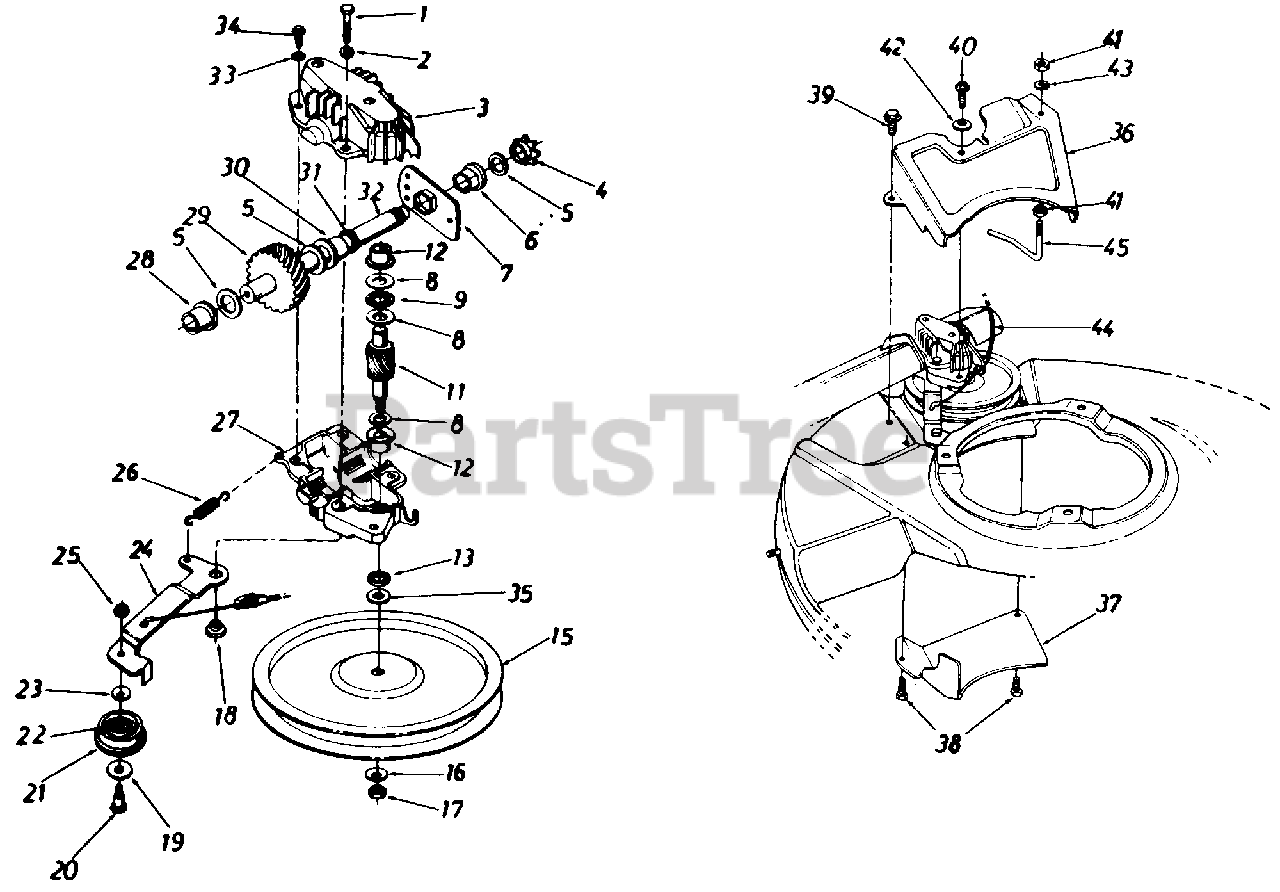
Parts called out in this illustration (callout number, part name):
1	Hex Bolt 1/4-20 x 1.25" Lg. w/Patch
2	L-Wash. 1/41" I.D.
3	Upper Hsg. Half
4	#48 Sprocket 7 Tooth x 1/2 Pitch
5	Fl-Wash. 518" I.D. x .030
6	Hex Flange Brg. .631" I.D.
8	Thrust Wash. .382" I.D. x .70" O.D.
9	Thrust Bearing .375" I.D. x.812" O.D.
11	11 Tooth Helical Gear
12	Flange Bearing
15	Fl-Pulley 5.06" I.D.
16	Bell-Wash. .265" I.D. x 75"
17	Hex Nut 1/4-28 L.H. Thd.
18	Shld. Spacer .375" Dia. x .170
19	Fl-Wash. .390" I.D. x 1.0"
20	Shld. Bolt .375" Dia. x .40"
21	Fl-ldler Plastic 1.50" Dia.
22	Needle Brg. .375" x .31"
23	Bell-Wash. .265" I.D. x .75"
24	Idler Brk't. Ass'y t
25	Hex Patch L-Nut 1/4-28 Thd.
26	Extension Spring 1.12" Lg.
27	Lower Hsg. Half
28	Flange Bearing .56 Dia.
29	33 Tooth Helical Gear
30	Flange Bearing .629 Dia.
31	Oil Seal .625 Dia.
32	Gear Sprocket Shaft
33	L-Wash. #10 I.D.
34	Hex B-Tap Scr. #10 x .62"
35	Hex Washer .26" x .88n
39	Hex AB-Tap Scr. 1/4 x 50n Lg.
40	Hex B-Tap Scr. 1/4 x .62" Lg.
41	Hex Nut 1/4-20 Thd.
42	Bell-Wash. .265" I.D. x .75"
43	L-Wash. 1/4" I D
44	S.P. Cable-48" Lg.
45	S.P. Belt Guard
